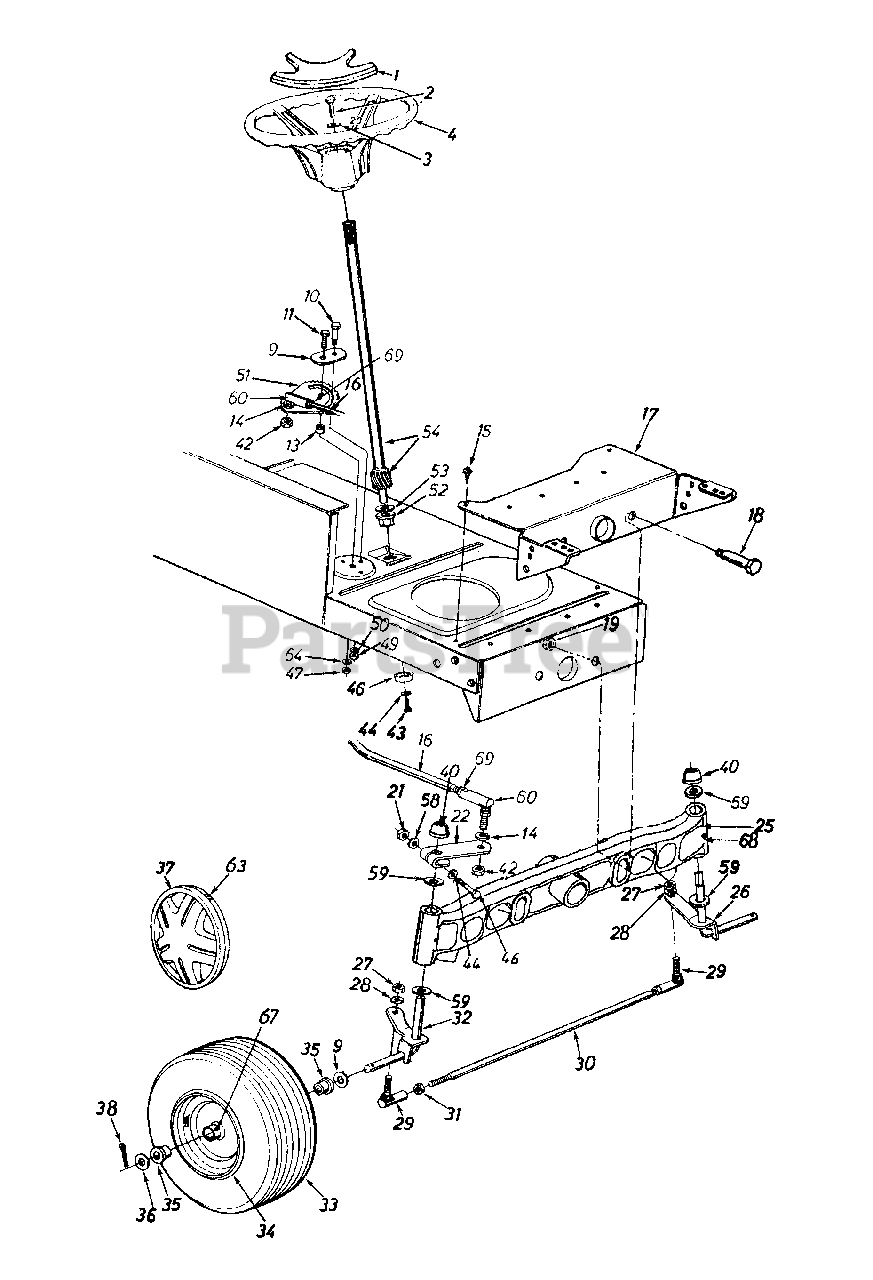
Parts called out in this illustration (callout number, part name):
1	Steering Wheel Cap
2	Hex Bolt 5/16-18 x 1" Lg.
3	Belleville Wash. .345" I.D.
4	Steering Wheel
9	Retainer Plate
10	Shld Bolt .437" Dia. x .35" Lg.-5/16-18
11	Hex Bolt 3/8-24 x 1.0" Lg. (Grade 5)
13	Spacer .380" I.D. x .625" O.D. x .227
14	L-Wash. 3/8" I.D. (H.D.)
15	Hex Wash. Hd. Self-Tap Scr.
16	Steering Drag Link
18	Shld Bolt .498" Dia. x 2.04" Lg.-3/8-16
19	Flanged Hex Nut 3/8-16 Thd.
21	Hex L-Nut 5/16-24 Thd.
22	Steering Arm Front Axle
25	Pivot Bar Ass'y.
26	Front Axle Ass'y.-L.H.
27	Hex Nut 3/8-24 Thd.
28	L-Wash. 3/8" I.D.
29	Ball Joint 3/8-24 Thd.
31	Hex Jam Nut 3/8-24 Thd.
32	Front Axle Ass'y.-R.H.
36	Fl-Wash. .635" I.D. x 1.59" O.D.
37	Hub Cap
38	Cotter Pin 1/8" Dia. x 1.25"
40	Push Cap 5/8" Dia. Rod
42	Hex Jam Nut 3/8-24 Thd.
43	Torx Bolt 5/16-18 x .63" Lg.
44	L-Wash. 5/16" I.D.
46	Cap
47	Hex Cent. L-Nut 3/8-24 Thd.
49	Hex Cent. L-Nut 5/16-18 Thd.
50	L-Wash. 5/16" I.D.
51	Steering Gear Segment
52	Hex. Flg. Brg. 5/8" I.D.
53	Fl-Wash. (Hardened)
54	Steering Shaft
58	Wave-Wash. .32" I.D. x .62" O.D.
59	Fl-Wash. (Hardened)
60	Drag Link Ball Joint 7/16-20 Thd.
63	Spring Clip
64	Bell-Wash. .39" I.D. x 1.38" O.D.
67	Grease Fitting
68	Grease Fitting
69	Hex Jam Nut 7/16-20 Thd.
